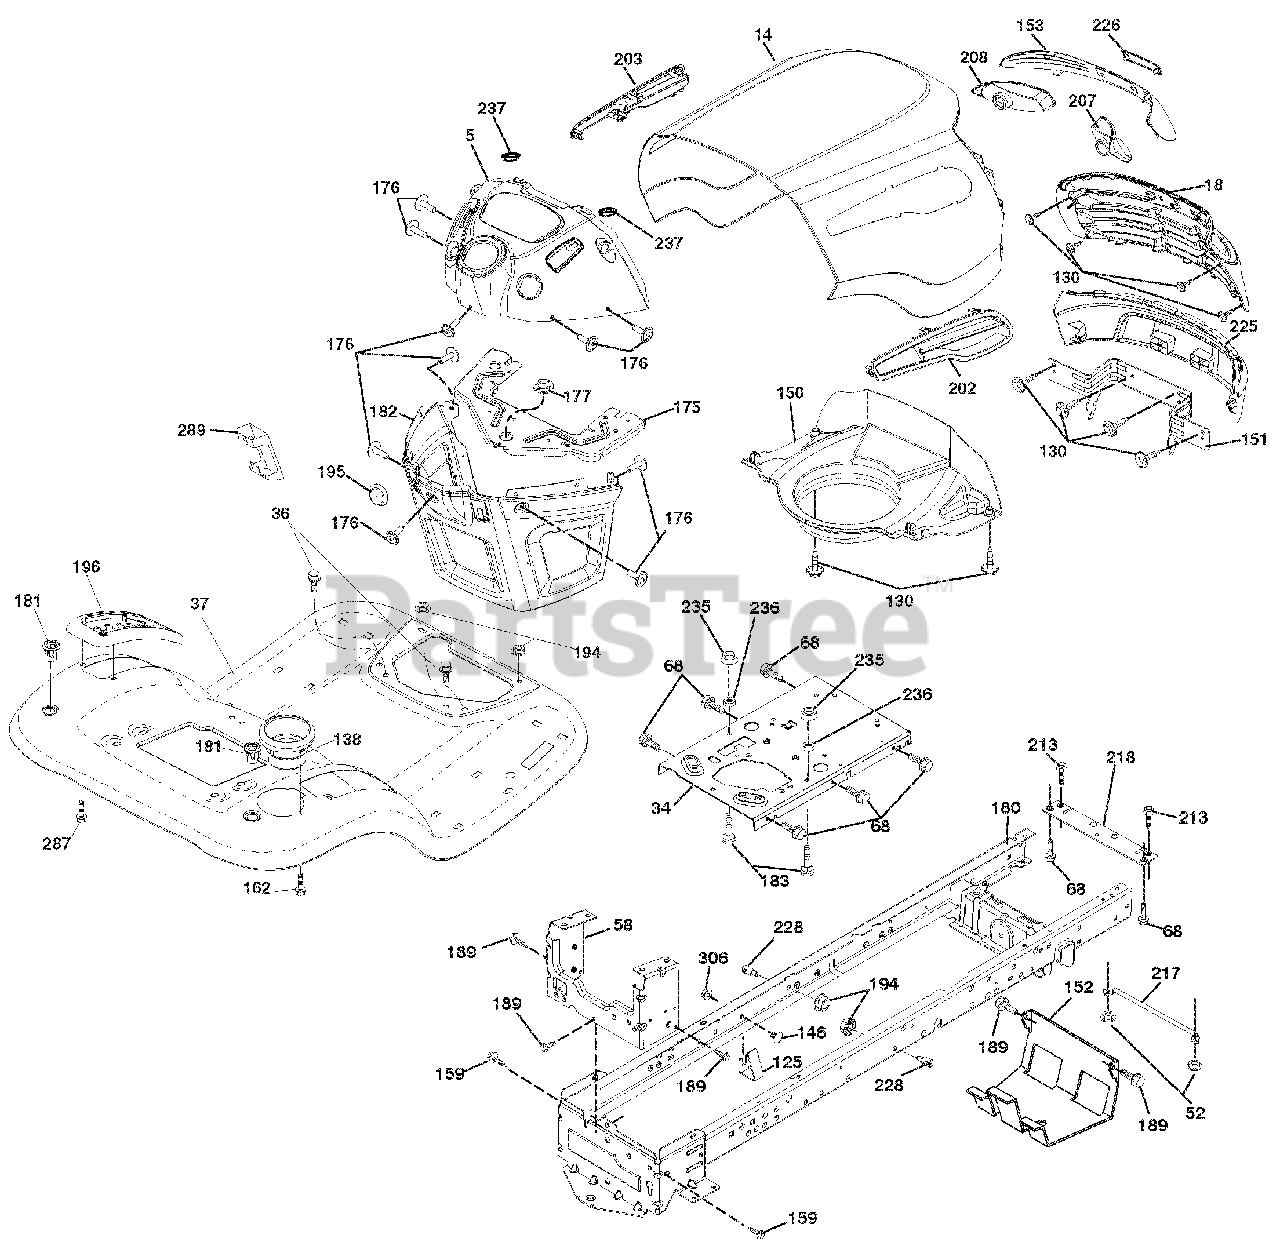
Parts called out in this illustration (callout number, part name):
5	DASH.P/L.TEX.CABLE
18	GRILLE.ELITE.ARIENS.BLACK
34	PLATE.ENGINE.WELDED.CHASSIS
36	SCREW.5/16-18X3/4.SMGML.TAP/R
37	FENDER TLT W/CPH W/FW 422
52	Nut, Hex, Crownlock 5/16-18
58	DRAWBAR.UPPER.2PC.SML.FENDER
68	SCREW.THDROL.5/16-18 X 1/2TYTT
125	CLIP.FUEL.LINE
138	CUPHOLDER TL TEX 428
150	AIR DUCT
151	BRACKET.PIVOT
152	SHIELD.BROWNING.W/TEX
153	LENS.BAR
159	SCREW.HEXWSH THDR3/8-16X3/4.BL
162	SCREW.HEX.WSH.HI-LO.1/4X1/2UNC
175	CROSSMEMBER.LT
176	SCREW.#10-24X5/8.RND.QUDRX.GIM
177	BUSHING.STEERING.LT
180	CHASS.WLDMT.TL.12GA/2PC.18/22"
181	BUSHING MNT FEND CRGO BLK TEX
182	DASH.LOWER.LT.CCS
183	BOLT.FIN.HEX.5/16-18 UNC X1-1/
189	SCREW.5/16-18X3/4.SMGML.TAP/BL
194	Nut, Lock Hex Flange 5/16-18 u
195	PLUG HOLE DASH TOWER
196	CONSLE.ASM.DECK.LFT.BL/RBT.TLT
202	VENT RH
203	VENT.SIDE.LH
207	BEZEL.RH
208	BEZEL.LH
213	BOLT.HEX.HD.1/4-20UNC X 3/4
217	ROD.PIVOT.HOOD
218	X-PIECE.HOOD.STOP.NON/STEALTH
226	ARIENS.LOGO.PLATE
228	STUD.FASTNER.W/'D'ANTI-ROTATIO
235	SPACER.FENDER
236	NUT.CENTER LOCK.5/16-18 UNC
237	PLUG.MOUNT.CARGO
287	SCREW.HEX.WASHEAD.1/4-20 X 3/8
289	PLUG.CRUISE.CONTROL
306	Nut, Hex, Flangelock 3/8-16
